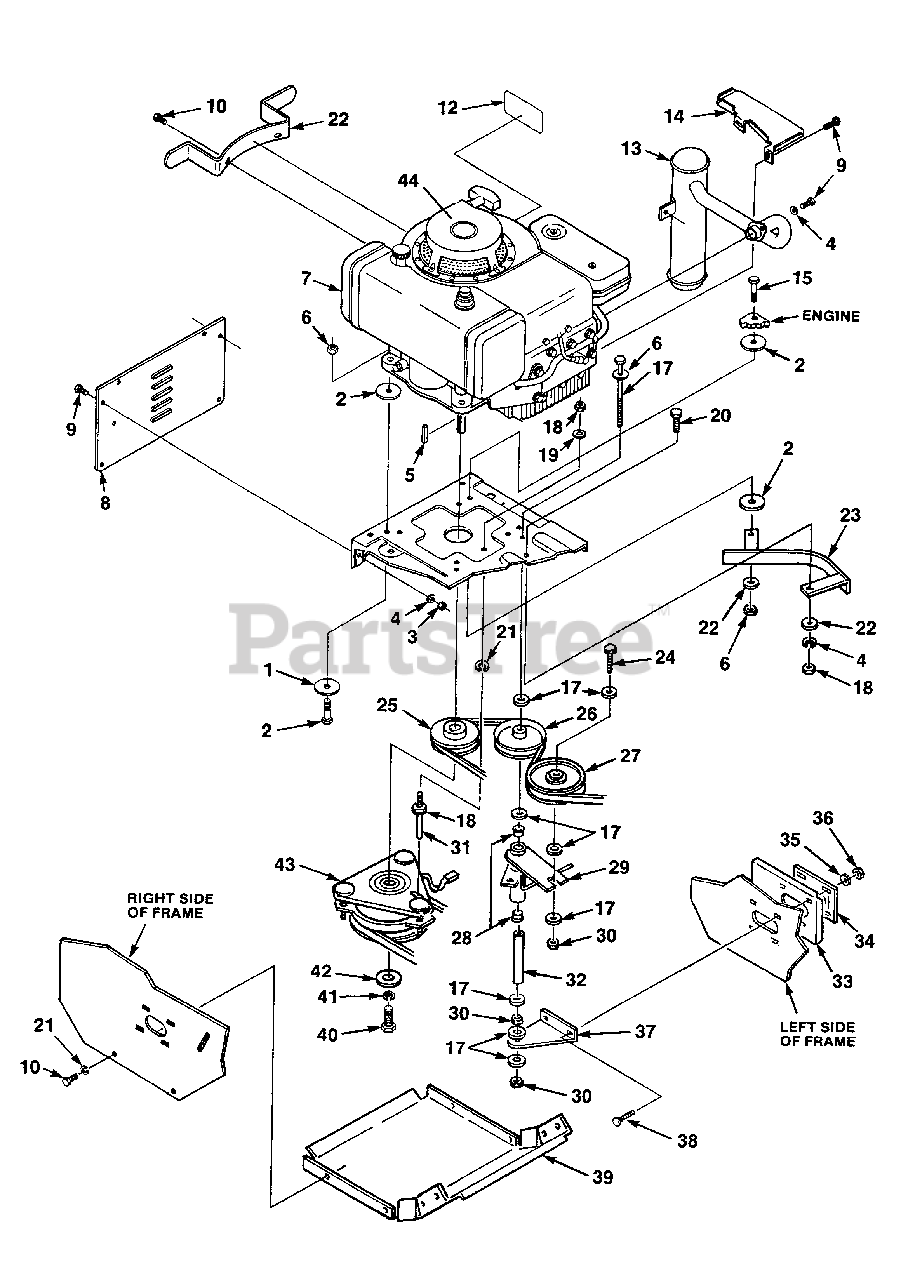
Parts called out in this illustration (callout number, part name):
1	SCREW- 5/16-18 x 1 1/2
3	NUT- 1/4-20 hex
4	WASHER- 5/16
5	KEY- 114 x 1/4 x 1
6	NUT- Lock 5/16 x 18
7	ENGINE-
8	PANEL- Rear
9	BOLT- 5/16-18 x 3/4
10	SCREW- 1/4-20 x 5/8
12	DECAL- (Hot Muffler)
13	MUFFLER
14	MUFFLER SHIELD
15	BOLT- 5/16-18 x 1 3/4
16	BOLT- 3/8-16 x 5 1/2
17	WASHER- 3/8 flat
18	NUT- Hex 5/16-18
19	WASHER- Flat 5/16
20	BOLT- 5/16-18
21	WASHER- Lock 5/16
22	WASHER- Flat 1/4
23	BELT- Guide
24	BOLT- 3/8-16 x 1 3/4
25	PULLEY- Engine
26	PULLEY- Idler
27	PULLEY- Idler
28	BEARING- Flange
29	ARM- Pivot
30	NUT- Hex Centerlock 3/8-16
31	PIN- Clutch torx
33	SUPPORT- Frame
34	RETAINER & BEARING
35	WASHER- Plain
36	NUT- Centerlock hex 1/4-20
38	BOLT- Rd. hd. carr. 1/4-20 x.750
39	PAN- Bottom
40	BOLT- Hex hd. 7/16-20 x 2 3/4
41	WASHER- Lock 7/16
42	CLUTCH RETAINER
43	CLUTCH- Warner
44	DECAL- 8 HP
